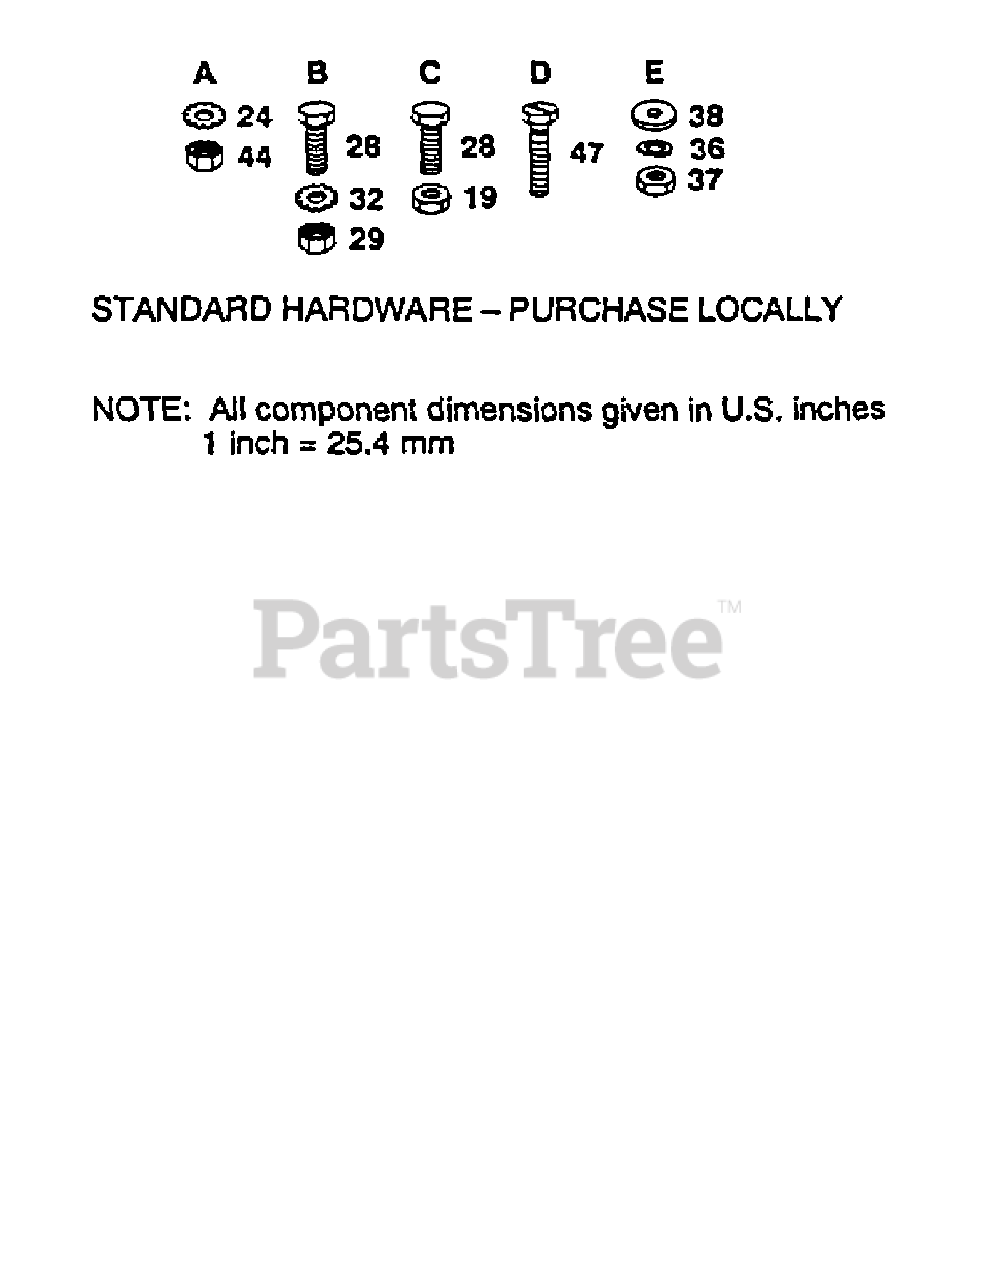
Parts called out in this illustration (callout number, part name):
19	NUT.CROWNLOCK.1/4
28	BOLT
29	NUT
32	LOCKWASHER
38	WASHER
44	NUT
